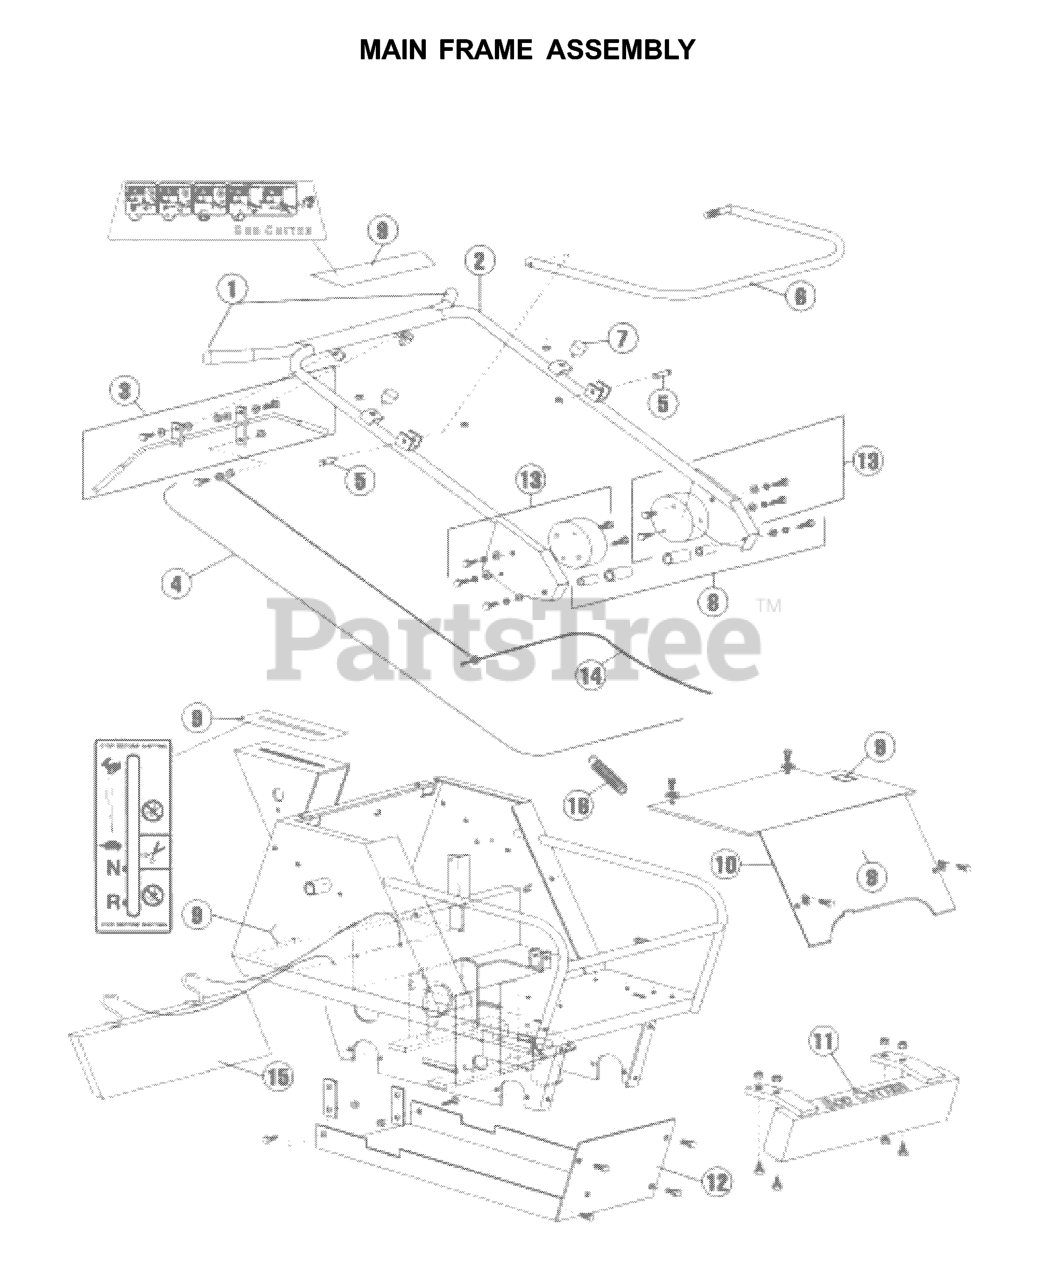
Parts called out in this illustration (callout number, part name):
1	GRIPS, PAIR, 1" ID, BLACK
2	HANDLE KIT
3	CLUTCH CONTROL KIT HUS
4	CABLE
5	PINS
6	DEPTH HANDLE GRAY
7	BUMPERS
8	STAND OFF KIT
10	SHIELD COVER KIT
11	WEIGHT ASSY W/ HARDWARE
12	SKID PAN FOR SC18
13	HANDLE ATTACHMENT KIT
14	THROTTLE CABLE, CARB
15	DEFLECTOR
16	SPRING
